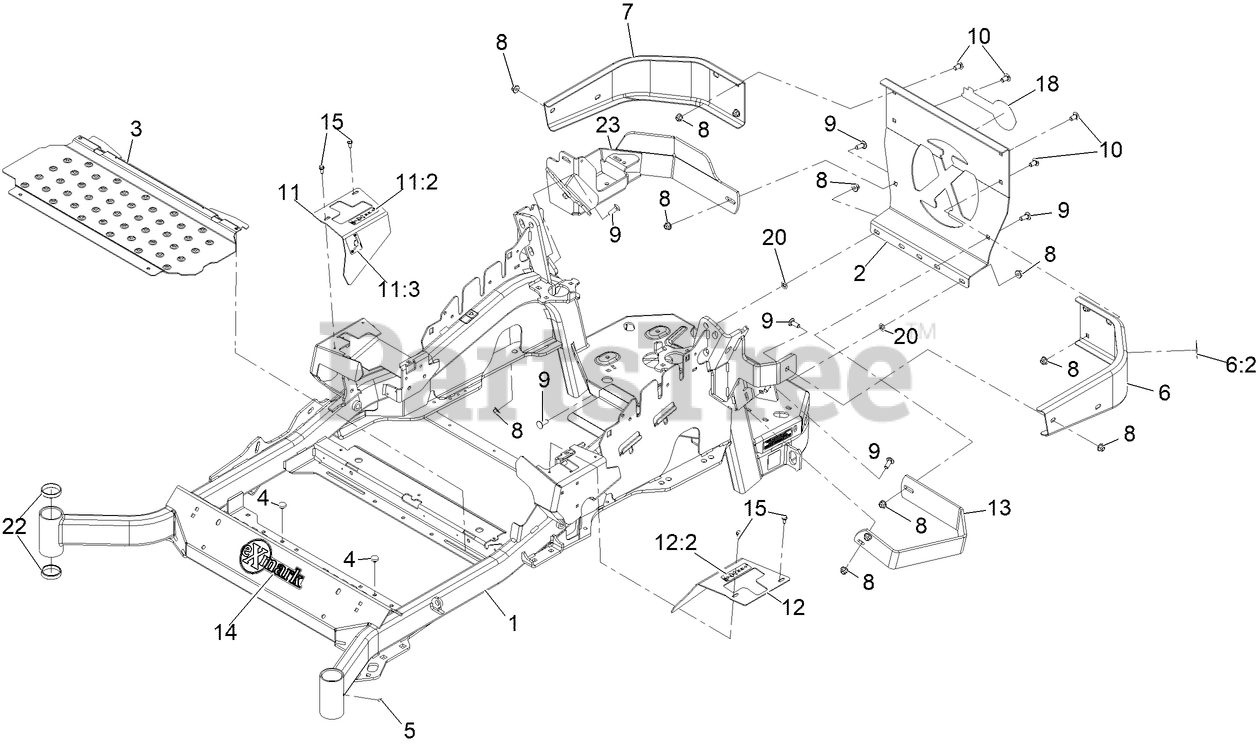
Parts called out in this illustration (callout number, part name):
1	MAINFRAME SERVICE ASM - 60
2	PLATE,REAR GUARD
6	LH BUMPER ASM
6:2	DECAL-WARNING
7	BUMPER-RH
8	NUT-HF, NI
9	SCREW-CARR
10	SCREW-CARR
11	RH MOTION CONTROL COVER ASM
11:2	DECAL-CONTROL, MOTION
11:3	DECAL-PARK BRAKE, CE
12	LH MOTION CONTROL COVER ASM
12:2	DECAL-CONTROL, MOTION
13	GUARD-MUFFLER
14	DECAL-EXMARK
15	SCREW-HWH
18	DECAL, EXMARK LOGO
20	NUT-PUSH
22	CUP-BEARING
23	BATTERY GUARD ASM
